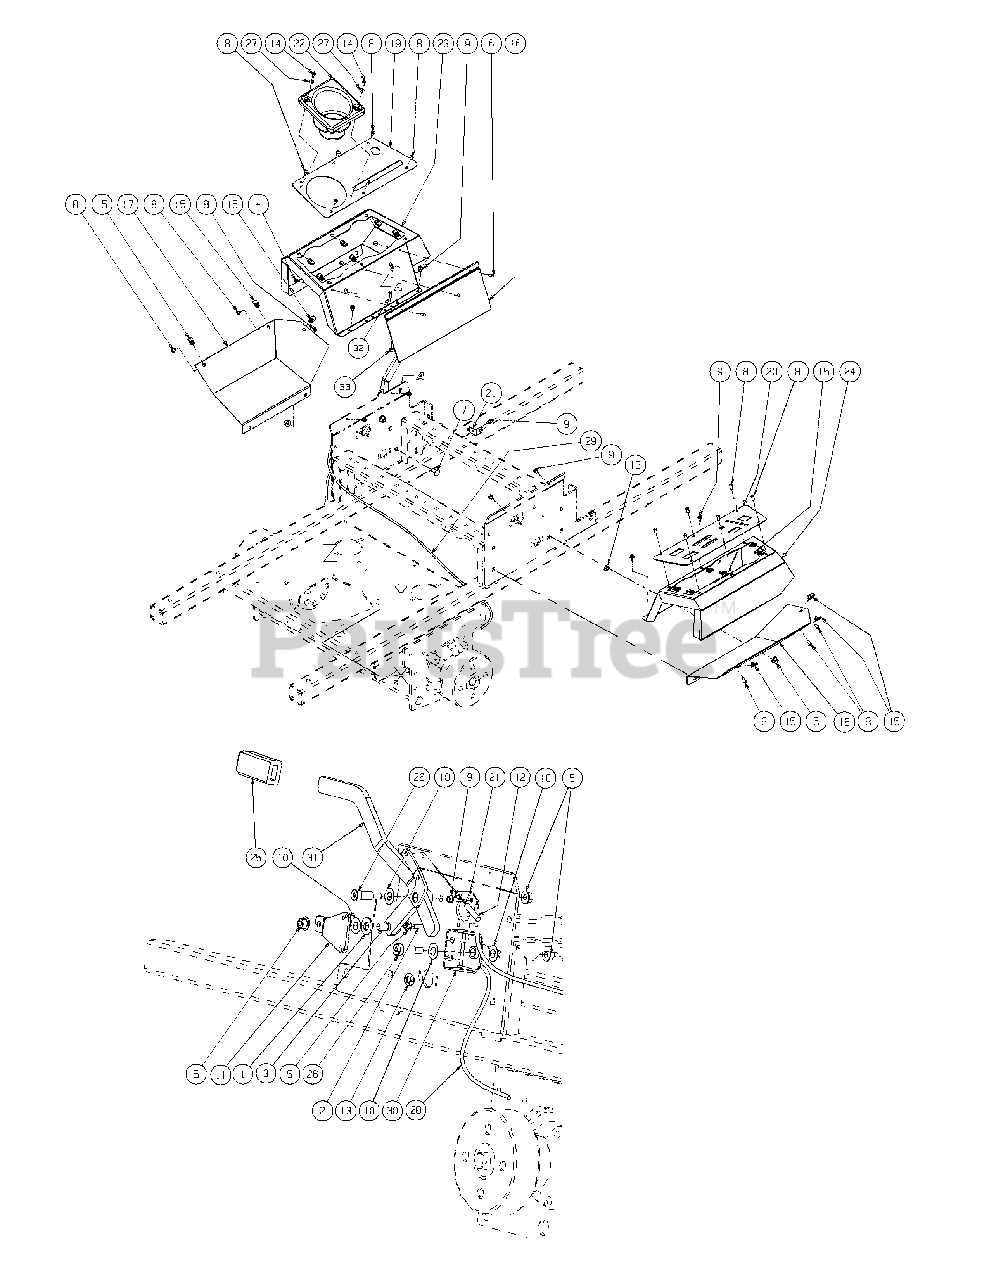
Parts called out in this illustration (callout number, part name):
1	Washer, 1/2 Zinc
2	Carriage Bolt, 3/8-16, 1.00
3	Shoulder Bolt, 1/2 x 1/2
4	Lock Nut, Nylon Insert, 10-32
5	Flange Lock Hex Nut, 3/8-16
6	Phillips Head Machine Screw, 10-32 x 5/8
7	Carriage Bolt, 3/8-16 x .75
8	Screw Button Head, 1/4-20 x .5
9	Screw, TT, 1/4-20, 0.5, Hex Index Washer
10	Washer, .508 ID x 1.0 OD x .020
11	Centering Bracket
12	Left Hand Brake Cable
13	Push Retainer, 3/8
14	Screw, #10-32 x 0.500
15	U-Nut, 1/4-20
16	Bag, Debris Storage
17	Lower Panel, LH
18	Lower Panel, RH
19	Control Panel Cover, LH
20	Control Panel Cover, RH
21	Brake Cable Mounting Bracket
22	Cup Holder
23	Control Panel, LH
24	Control Panel, RH
25	Parking Brake Grip
26	Shoulder Bolt, 1/2 x 1.00, 3/8-16
27	Washer, 3/16
28	Brake Cable, LH
29	Brake Cable, RH
30	Brake Cable Bracket
31	Brake Lever
32	Screw, Hex, Cap, 1/4-20 x .75
33	Lock Nut, 1/4-20
